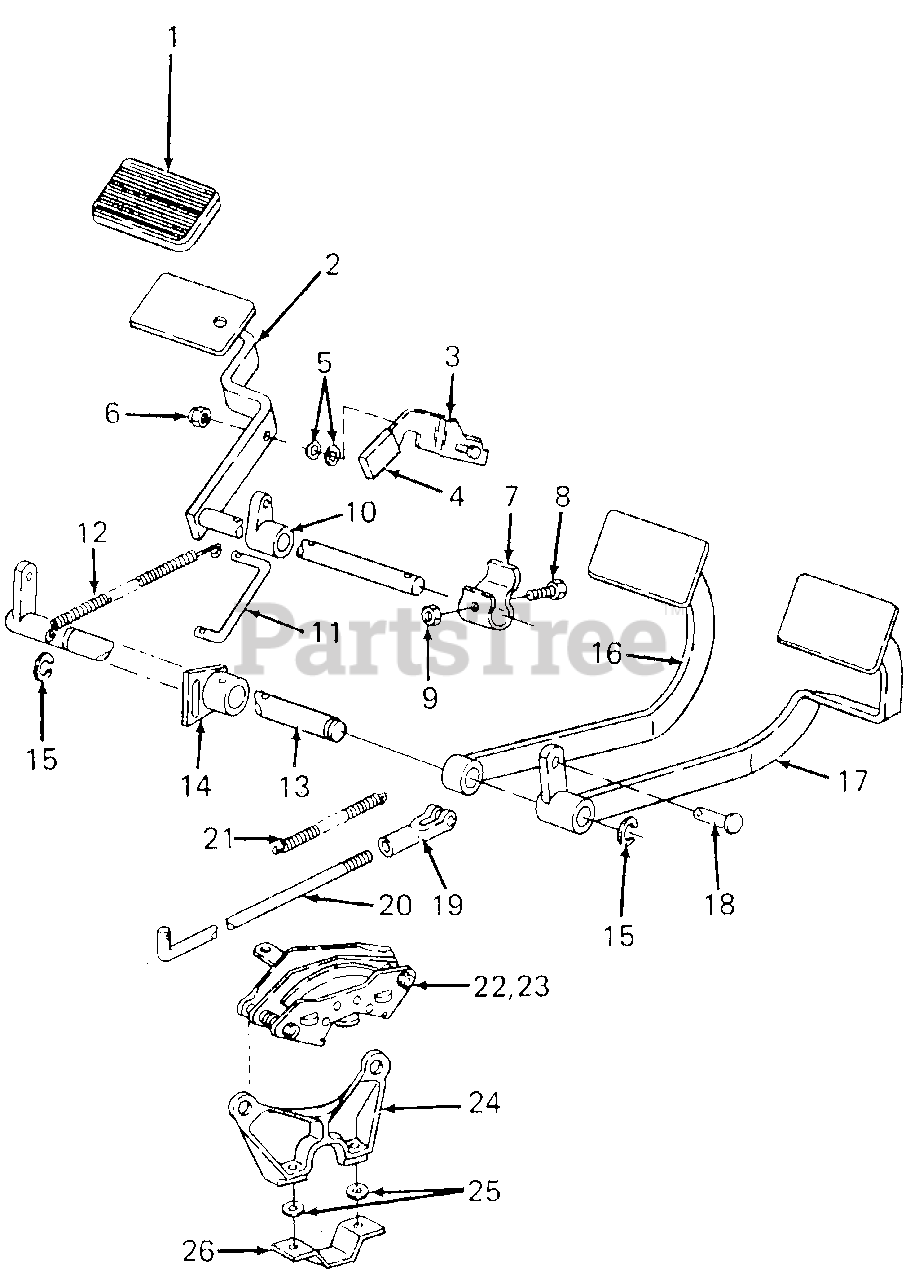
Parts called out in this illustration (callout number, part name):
1	Pad, Pedal
5	Washer, Wave, 1/4 Dia
6	Nut, Hex Insert Lock, 1/4-20
7	Spring, Switch Operating
8	Screw, Hex Cap, 1/4-20 X .75 Lg GR5
9	Nut, Hex Center Lock, 1/4-20
11	Rod, Center Brake
12	Spring, Extension, .50 OD X 7.32 Lg
13	Shaft Assy, Brake
14	Arm Assy, Parking Brake Plate
15	Ring, Retaining
18	Pin, Clevis, 3/8 Dia X 1.56 Lg
19	Clevis, Adjustment
20	Rod, Brake
21	Spring, Extension, .66 OD X 3.3 Lg
22	Brake Kit, LH - Caliper
23	Brake Kit, RH - Caliper
24	Bracket, Brake Mounting
25	Washer, Flat, .406 X .812 X .134 Thk
26	Bracket, Caliper Flange Mounting
